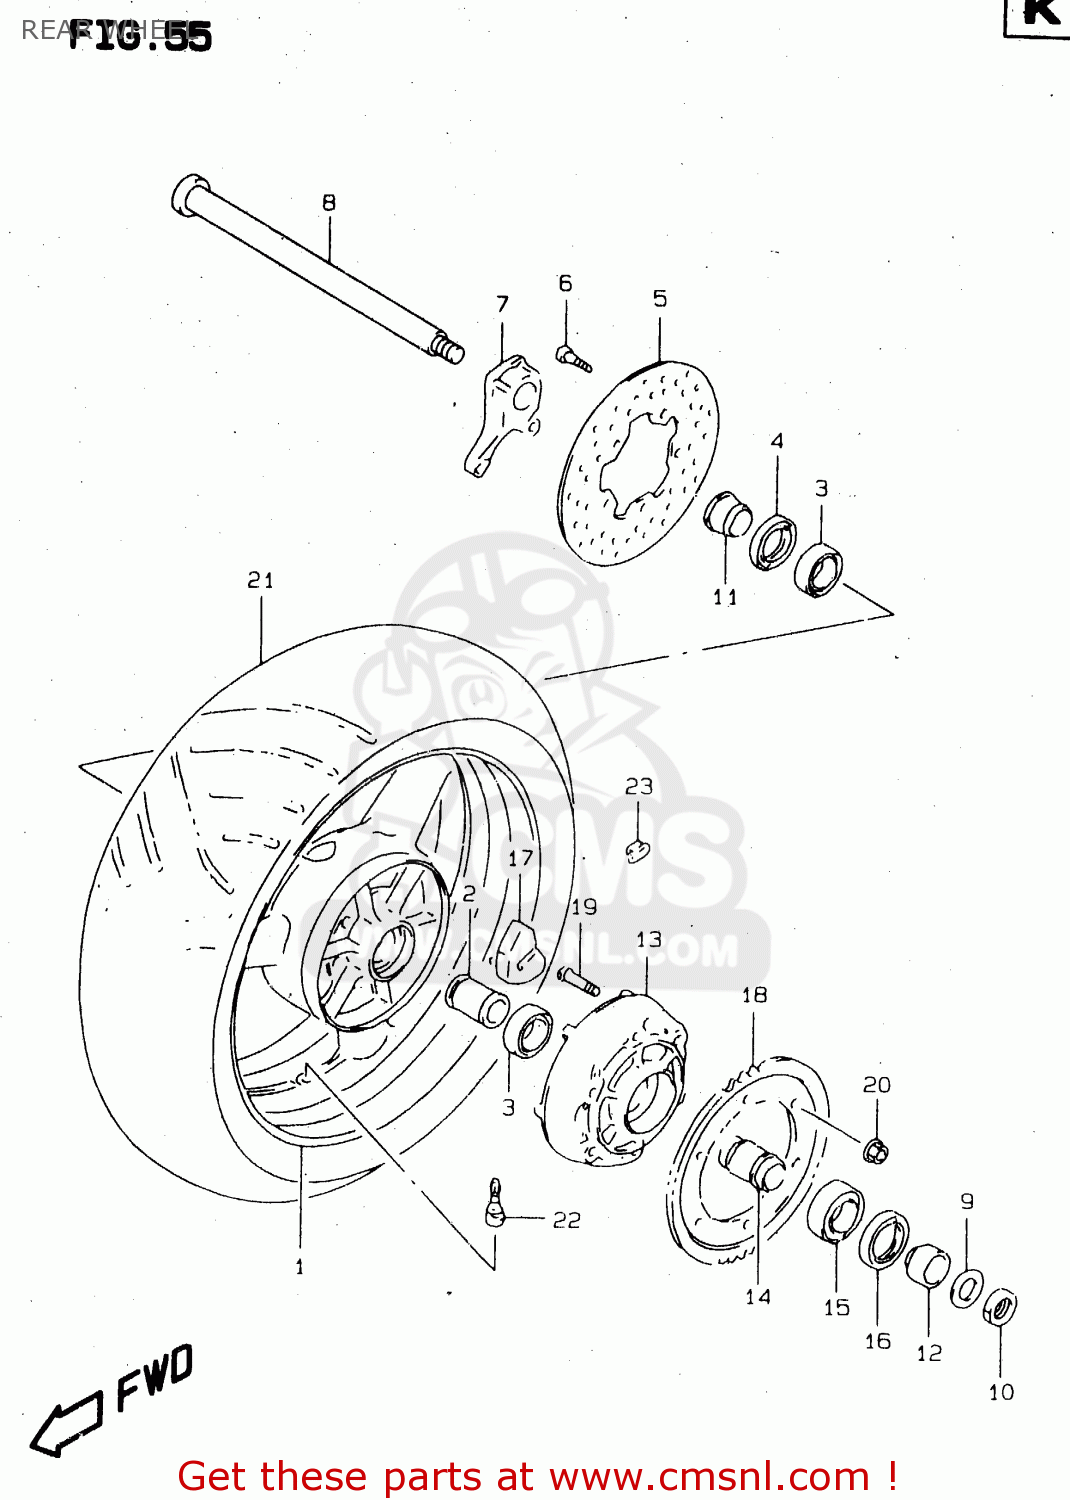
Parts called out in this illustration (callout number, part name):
1	WHEEL,REAR (17XMT6.00)
2	SPACER,RR HUB BEARING
3	BEARING(32X58X13)
4	SEAL,OIL(38X58X7)
5	DISC,RR BRAKE
6	BOLT 8X33
7	BRACKET,RR CALIPER
8	AXLE,RR
9	WASHER(25.2X42X3.2)
10	NUT
11	SPACER,RR AXLE,R
12	SPACER,RR AXLE,L
13	DRUM,RR SPROCKET
14	RETAINER,RR SPROCKET DRUM
15	BEARING
16	SEAL,OIL(39X65X7)
17	ABSORBER,RR HUB SHOCK
18	SPROCKET,RR(NT:38-530)
19	BOLT
20	NUT
21	TIRE,REAR 190/50 ZR17
22	VALVE ASSY,WHEEL RIM(TR412)
23	BALANCER,WHEEL (10G)
